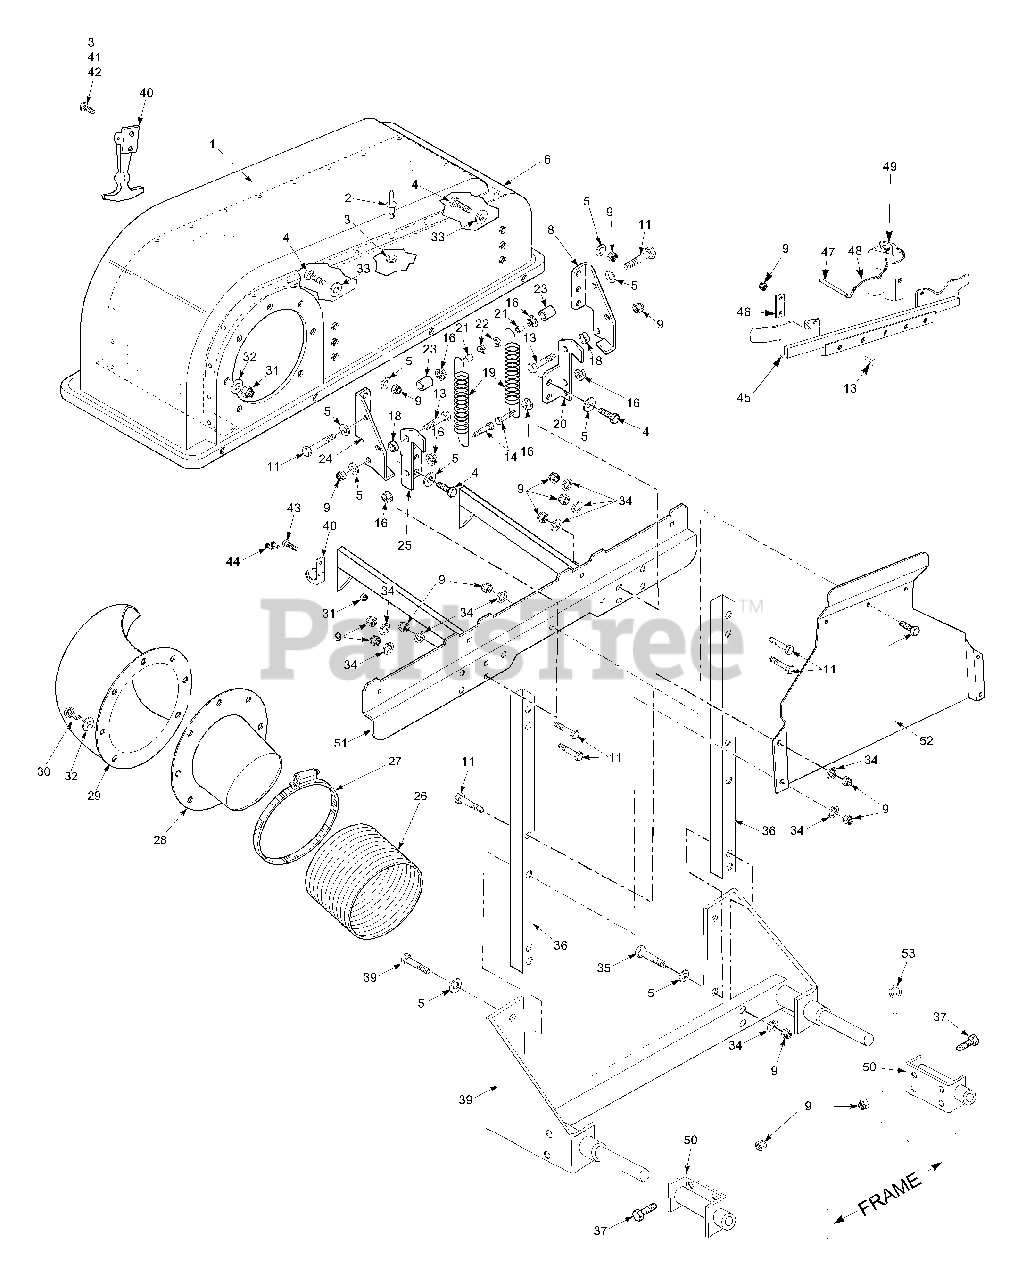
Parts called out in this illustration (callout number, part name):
1	Screen, Catcher Hood
2	Pop Rivet, 3/16 x .652
3	Flatwasher, 3/16-.196 x .469 x .048
4	Bolt, Hex Head 3/8-16 x 1-1/4"
5	Flatwasher, 3/8-.391 x .938 x .105
6	Hood Assembly, GC-STT
8	Hinge, Upper LH
9	Nut, Elastic Stop 3/8-16
11	Bolt, Hex Head 3/8-16 x 2-1/4"
13	Bolt, Hex Head 3/8-16 x 1-1/2"
14	Bolt, Hex Head 3/8-16 x 1-3/4" Grade 8
16	Nut, Serrated Flange 3/8-16
18	Bushing, Hopper Pivot
19	Spring, Hood Hinge
20	Hinge, Lower LH
21	Spacer
22	Locknut, 3/8-16
23	Spacer
24	Hinge, Upper RH
25	Hinge, Lower RH
26	Hose, 8" Dia. x 56"
27	Clamp, 8-5/8" Max Dia.
28	Tube, Filler GC-STT
29	Elbow, GC-STT
30	Bolt, Hex Head 5/16-18 x 1-1/4"
31	Nut, Elastic Stop 5/16-18
32	Flatwasher, 5/16-.375 x .875 x .083
33	Flatwasher, 3/8- .406 x 1-1/2" x .179
34	Lockwasher, 3/8 Spring
35	Bolt, Hex Head 3/8-16 x 3-3/4"
36	Tube, Upright
37	Bolt, Hex Head 3/8-16 x 1"
39	Bolt, Hex Head 3/8-16 x 2-1/2"
40	Latch
41	Screw, #10-32 x 3/4"
42	Nut, Elastic Stop #10-32
43	Bolt, Hex Head 5/16-18 x 3/4"
44	Rivet, 3/16 x .402 POP
45	Support Weldment, Front Weights
46	Clamp, Bar
47	Pin, 1/2 x 6-1/4"
48	Lanyard, Weight Pin
49	Weight Assembly
50	Hitch Bracket Weldment
51	Support Weldment, Bag Frame
52	Heat Shield
53	Quick Pin
